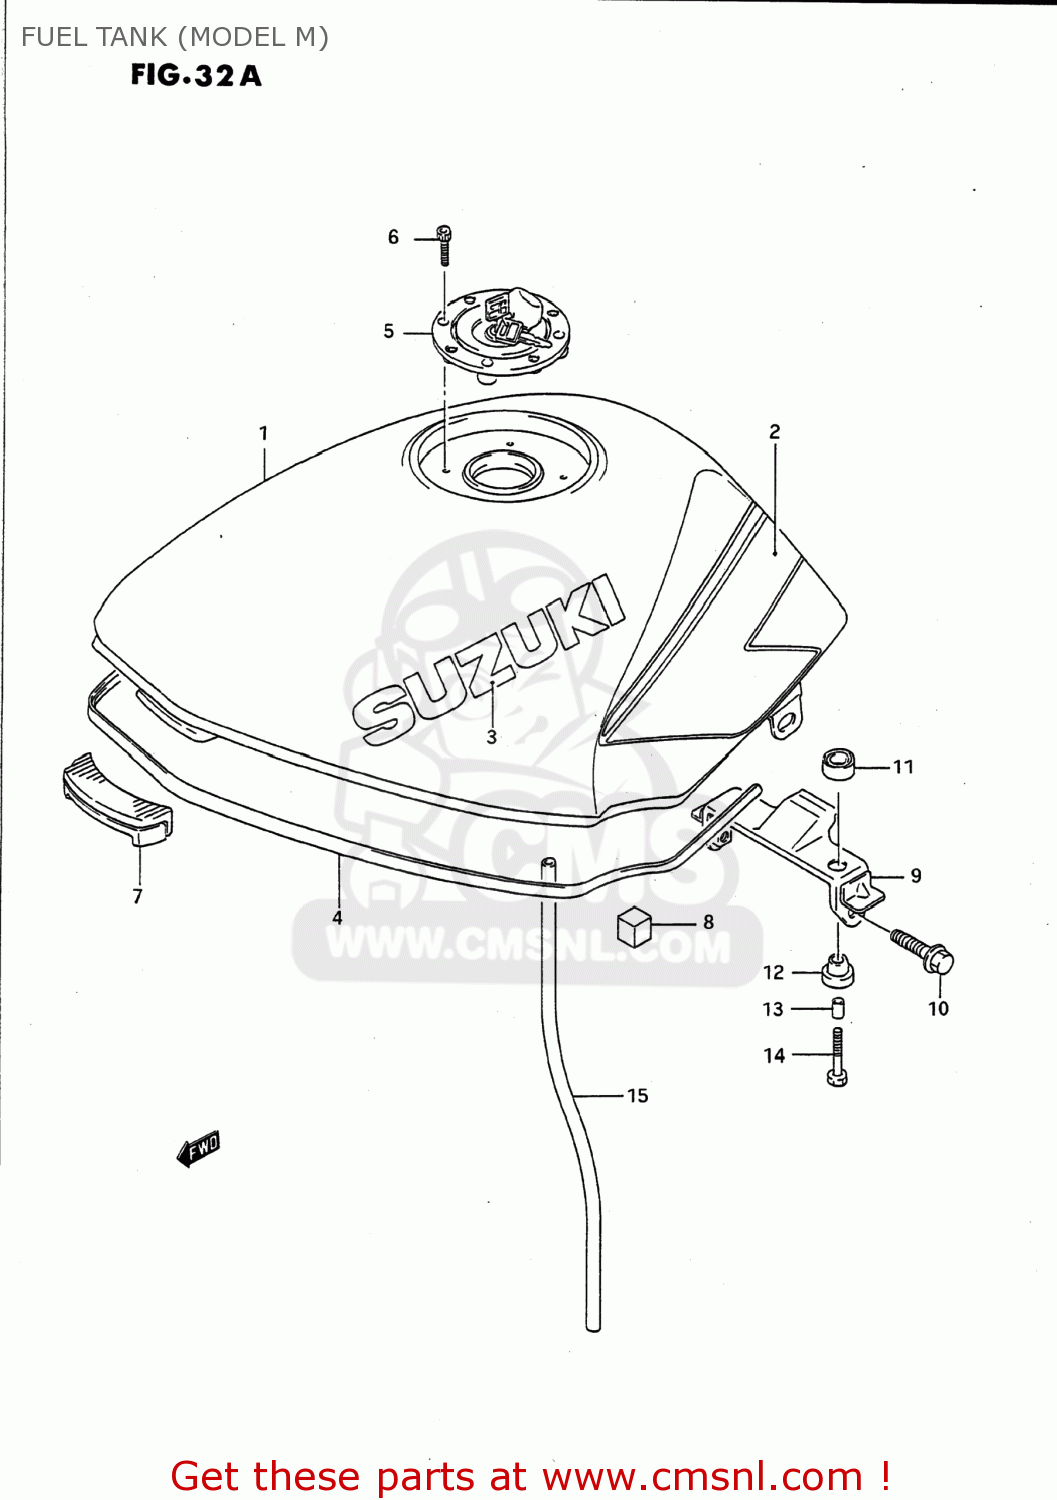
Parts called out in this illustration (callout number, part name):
1	TANK ASSEMBLY,FUEL
2	TAPE SET,FUEL TANK
3	EMBLEM,FUEL TANK
4	MOLDING
5	CAP SET,FUEL TANK
6	BOLT(5X20)
7	CUSHION,FUEL TANK FR
8	CUSHION,FUEL TANK SIDE
9	BRACKET COMP,FUEL TANK
10	BOLT
11	CUSHION
12	CUSHION
13	SPACER(6.1X9X18.2)
14	BOLT
15	HOSE,WATER DRAIN
